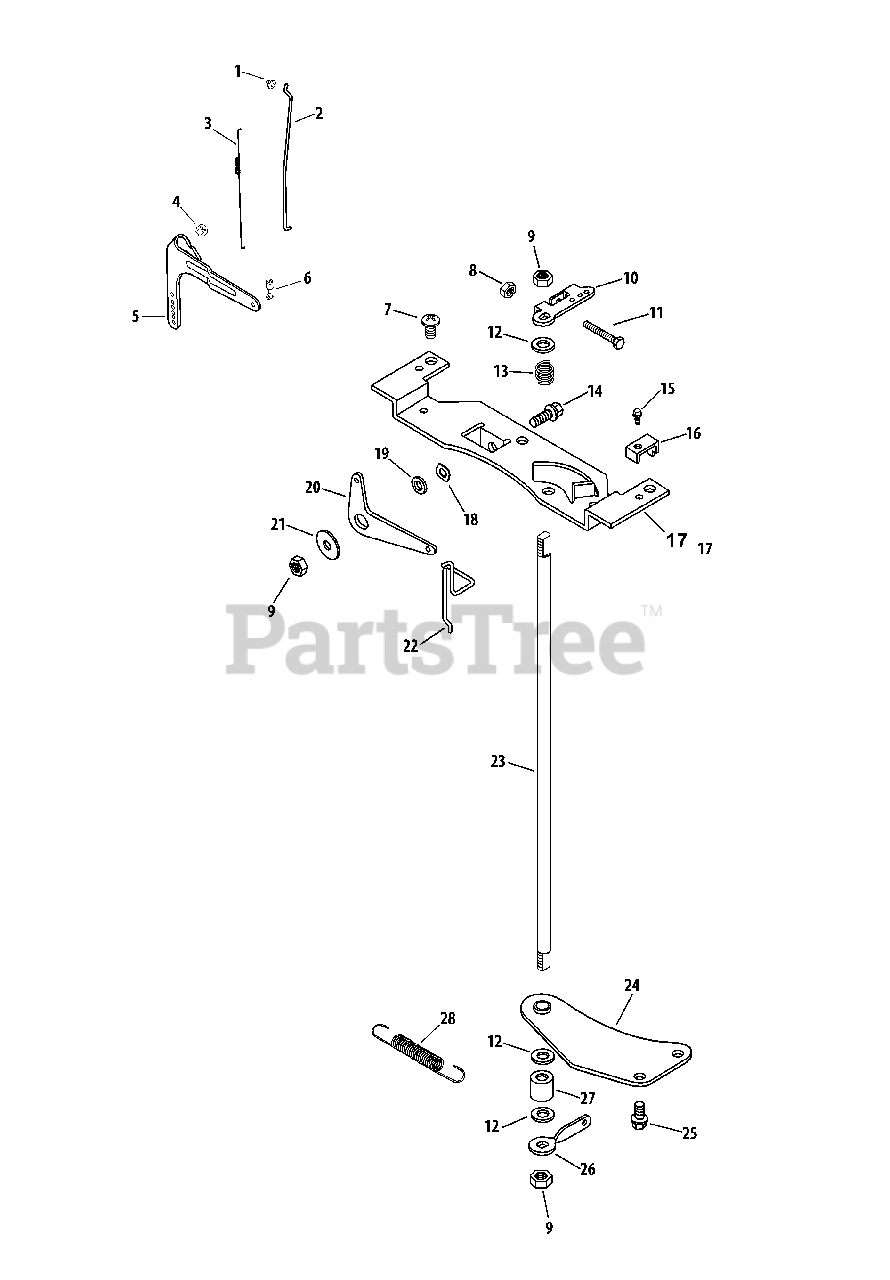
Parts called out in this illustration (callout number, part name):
1	Linkage Retaining Bushing
2	Throttle Linkage
3	Linkage Spring
4	Flange Nut, M6 x 1.0
5	Governor Lever
6	Throttle Linkage Bushing
7	Phillips Head Screw, 11-16 X 3/4
8	Nut, M4 x 0.7
9	Lock Nut, M6 x 1.0
10	Throttle Control Lever
11	Cap Screw, M4 x .7 X 30
12	Flat Washer, 1/4
13	Throttle Shaft Spring
14	Flange Screw, M6 x 1.0 x 16
15	Flange Screw, M5 x 0.8 x 16
16	Cable Clamp
17	Bracket Control
18	Spring Washer, 3/8
21	Flat Washer, 1/4
22	Choke Linkage
23	Throttle Shaft
24	Throttle Shaft Bracket
25	Flange Screw, M6 x 1.0 x 16
26	Throttle Control Lever
28	Governor Spring (Black)
